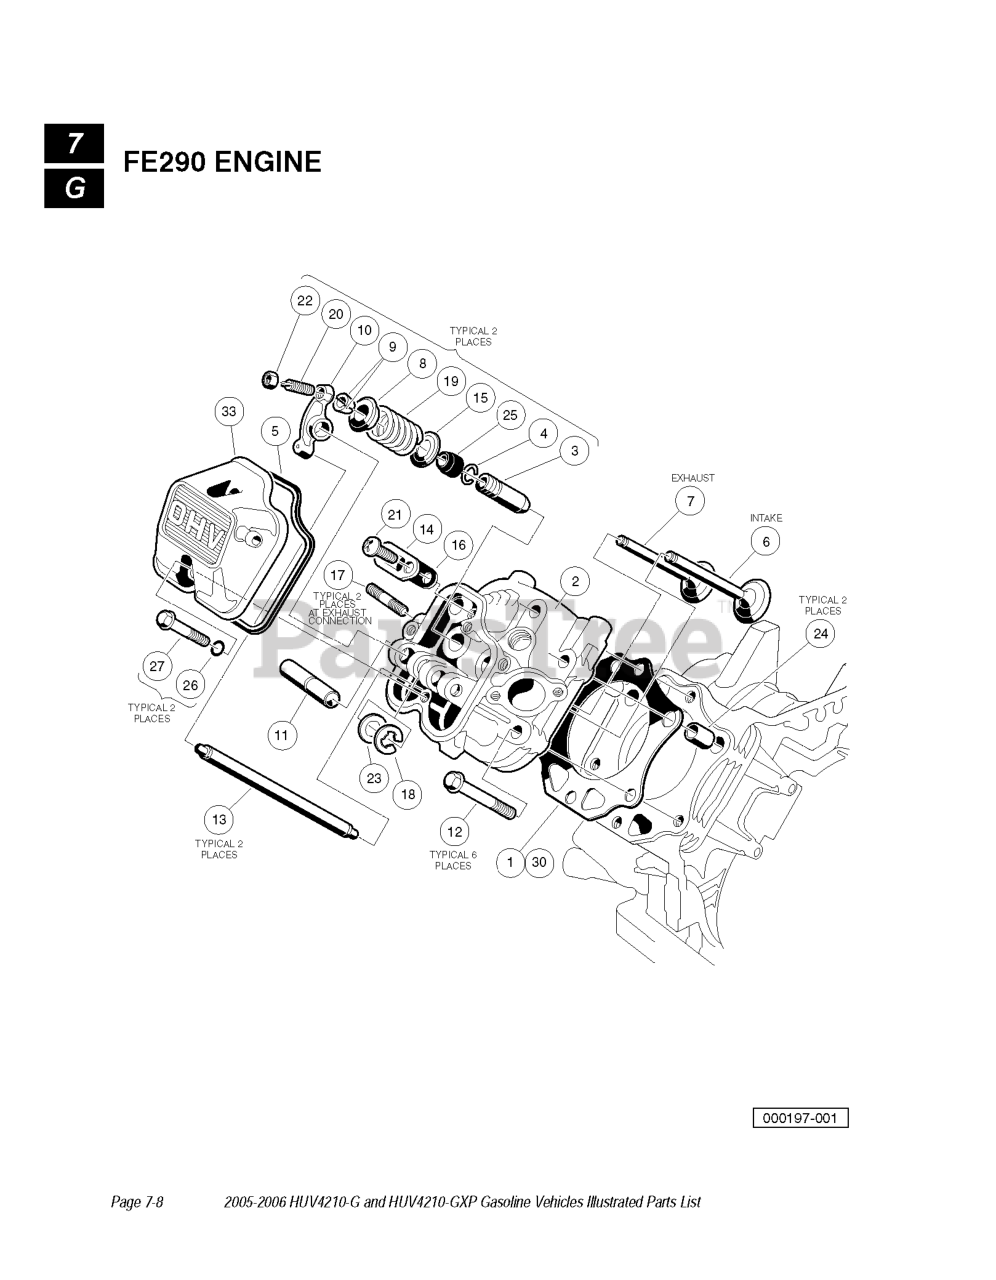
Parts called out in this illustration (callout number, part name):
1	GASKET, FE290 HEAD
2	HEAD ASSY, FE290 CYLINDER
3	GUIDE, VALVE, INTAKE
5	GASKET, ROCKER CASE
6	VALVE - INTAKE
7	VALVE - EXHAUST
8	RETAINER - VALVE SPRING
11	SHAFT - ROCKER
12	BOLT, FLANGED
15	SEAT, SPRING
17	STUD, M8-1.25 2-ENDED
18	CIRCLIP - TYPE - E
19	SPRING, ENGINE VALVE
23	WASHER, 12.1X19X1.8
27	BOLT, 6X35
28	GASKET KIT, FE290
29	GASKET, OHV EXHAUST
30	GASKET, FE290 HEAD
31	GASKET, ENGINE TO INSULATOR
32	GASKET, CRANKCASE COVER
33	CASE, ROCKER -W/O LOGO FE290
